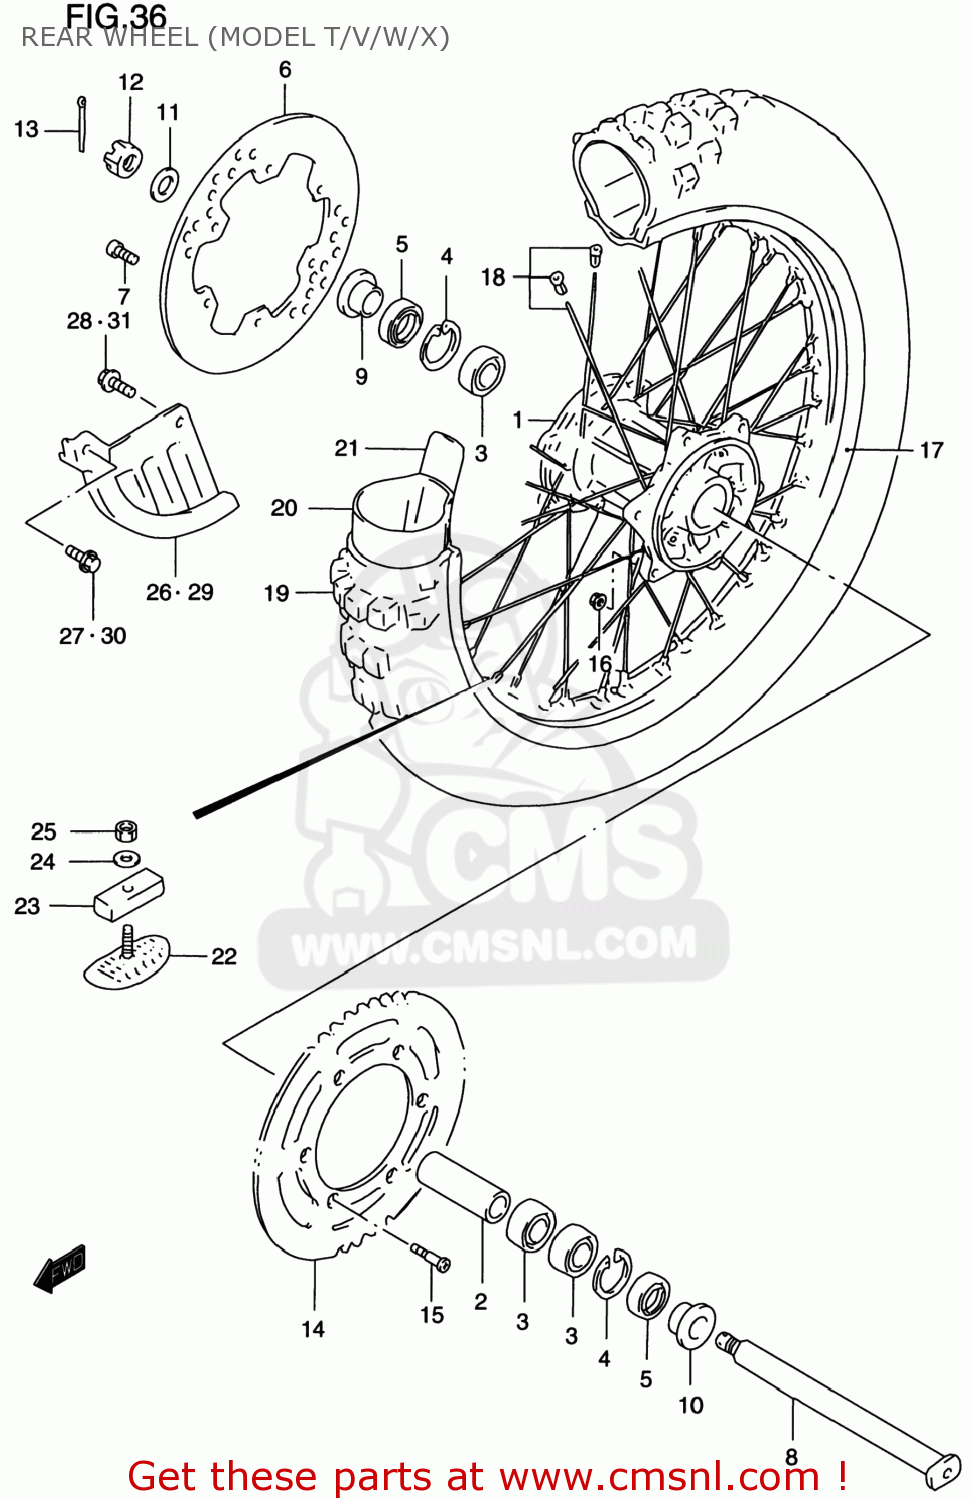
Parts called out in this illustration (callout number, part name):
1	HUB,RR WHEEL
2	SPACER,RR HUB BEARING
3	BEARING
4	CIRCLIP
5	SEAL(29X42X6)
6	DISC,RR BRAKE
7	SCREW
8	AXLE,RR
9	SPACER,RR AXLE
10	SPACER,RR AXLE
11	WASHER(19X32X3.2)
12	NUT
13	PIN,COTTER
14	SPROCKET,RR(NT:49)
15	BOLT(8X30.5)
16	NUT
17	RIM,REAR WHEEL (1.85X19)(A
18	SPOKE SET,RR WHEEL
19	TIRE,REAR 100/90-19
20	TUBE
21	PROTECTOR,WHL INR TUBE
22	STOPPER,BEAD(1.85)
23	CUSHION,BEAD STOPPER
24	WASHER
25	NUT
26	COVER SET,RR BRAKE DISC
27	BOLT
28	BOLT
29	COVER,REAR DISC
30	BOLT
31	BOLT
